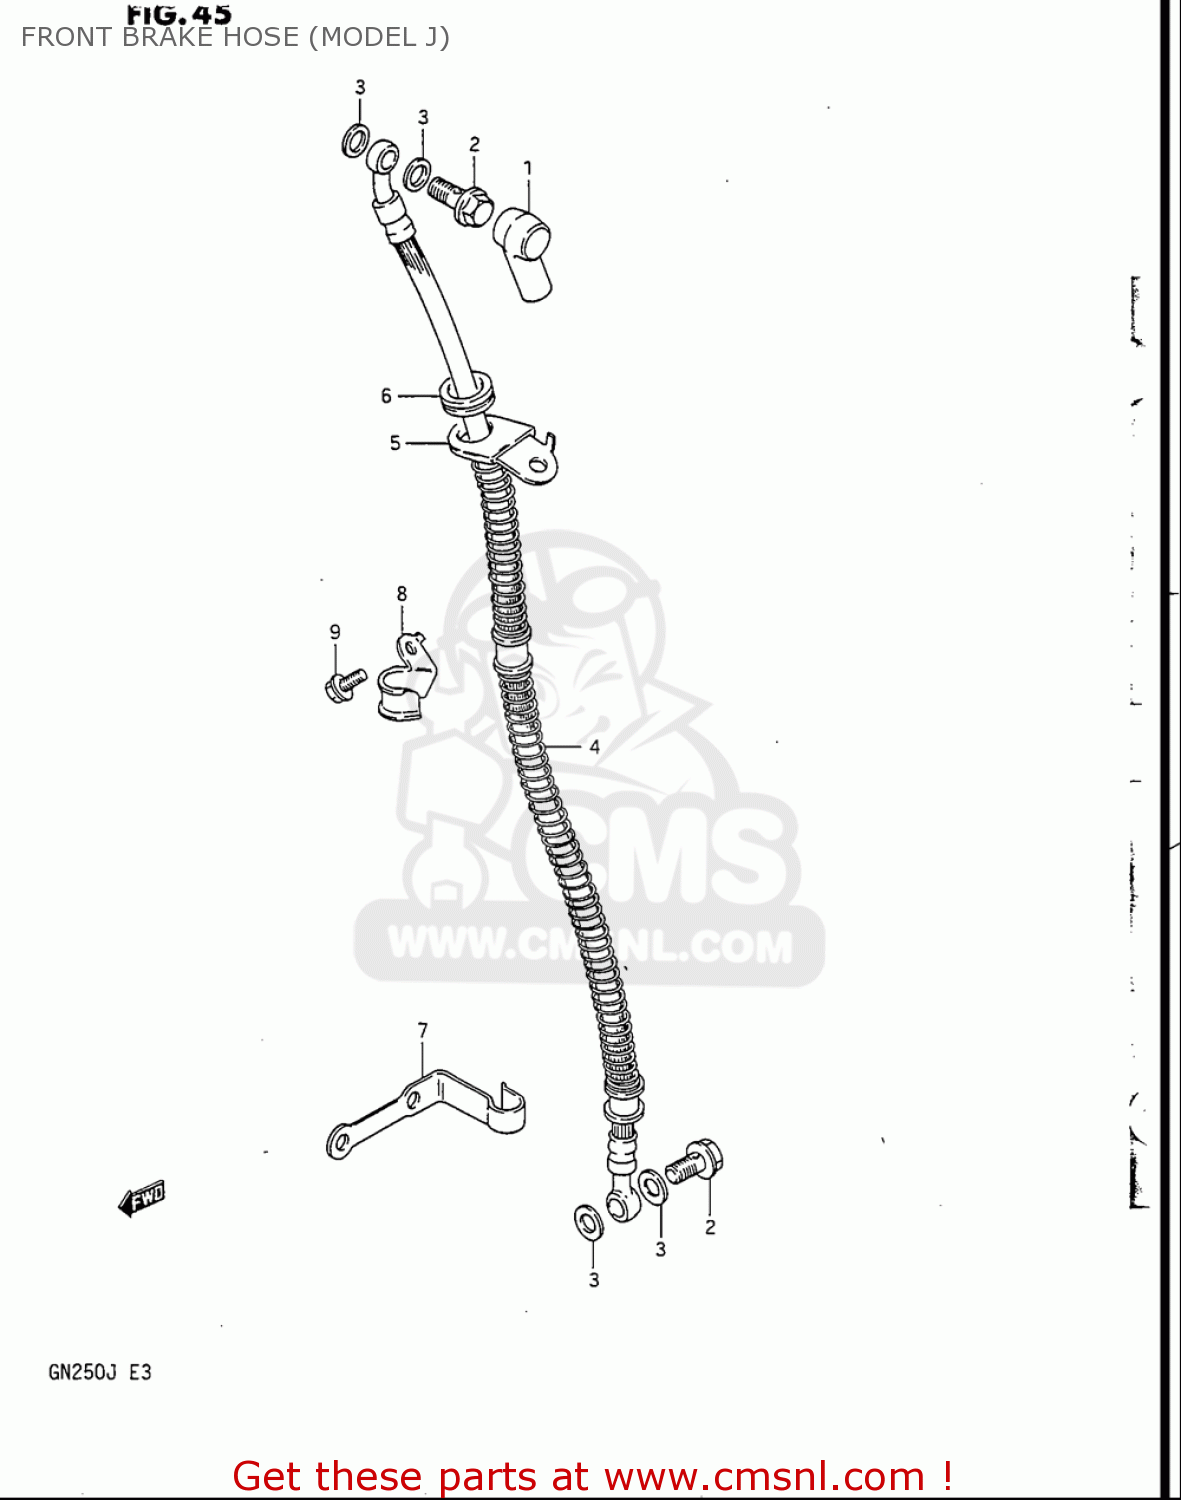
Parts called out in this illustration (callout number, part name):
1	BOOT,MASTER CYLINDER
2	BOLT UNION
3	WASHER(10X15X1.5)
4	HOSE,FR BRAKE
5	GUIDE,BRAKE HOSE
6	GROMMET
8	GUIDE,BRAKE HOSE NO.3
9	BOLT
